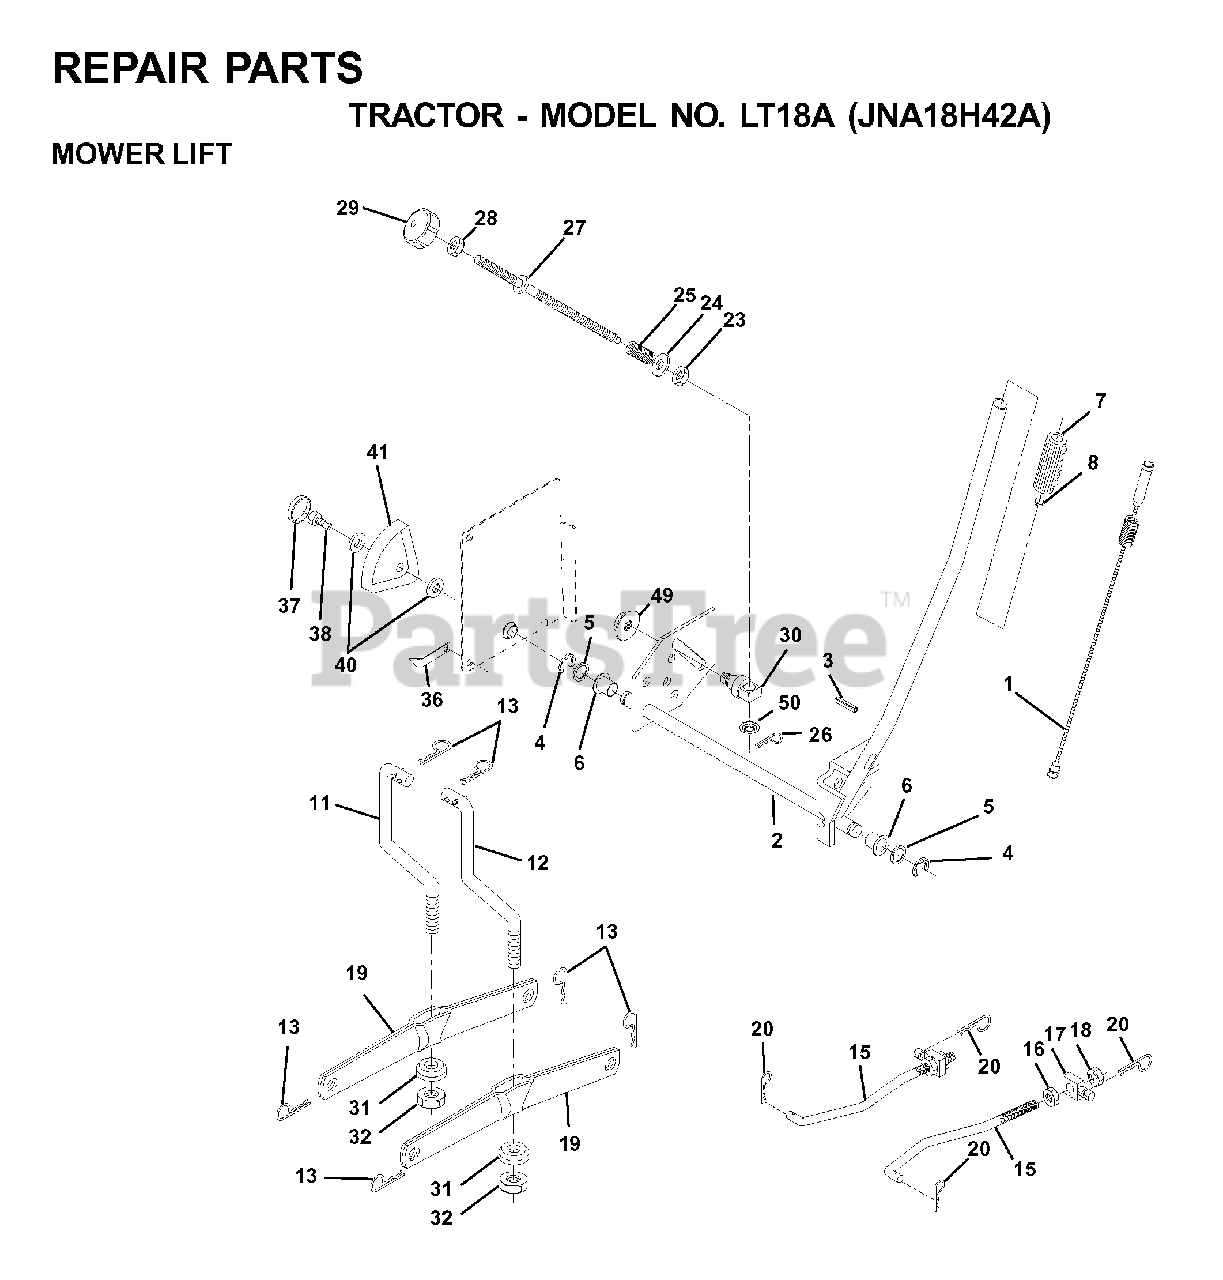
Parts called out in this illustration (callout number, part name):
1	WIRE ASM INNER W/ PLUNGER LT
2	SHAFT ASM R HANDLE
3	PIN GROOVE
4	RETAINING RING LT
6	BEARING.NYLON
7	GRIP HANDLE
8	PLUNGER BUT KIT
11	LINK LIFT LH
12	LINK LIFT RH
13	RETAINER-SPRNG RB
15	LINK.SUSPENSION.FRONT
16	NUT
17	TRUNION
18	NUT
19	ARM.REAR.SUSPENSION
20	SPRING RETAINER
25	SPRING**
26	RETAINER CLIP
27	ROD ADJ LIFT
28	NUT
29	KNOB INF 3/8-16
31	BEARING.PIVOT.LIFT
32	NUT CROWNLOCK 3/8-24
36	POINTER, HEIGHT INDICATOR
37	PLUG,HOLE
38	SCREW 5/16-18X1
41	IND. HEIGHT STLT
49	NUT
50	NUT PUSH M
